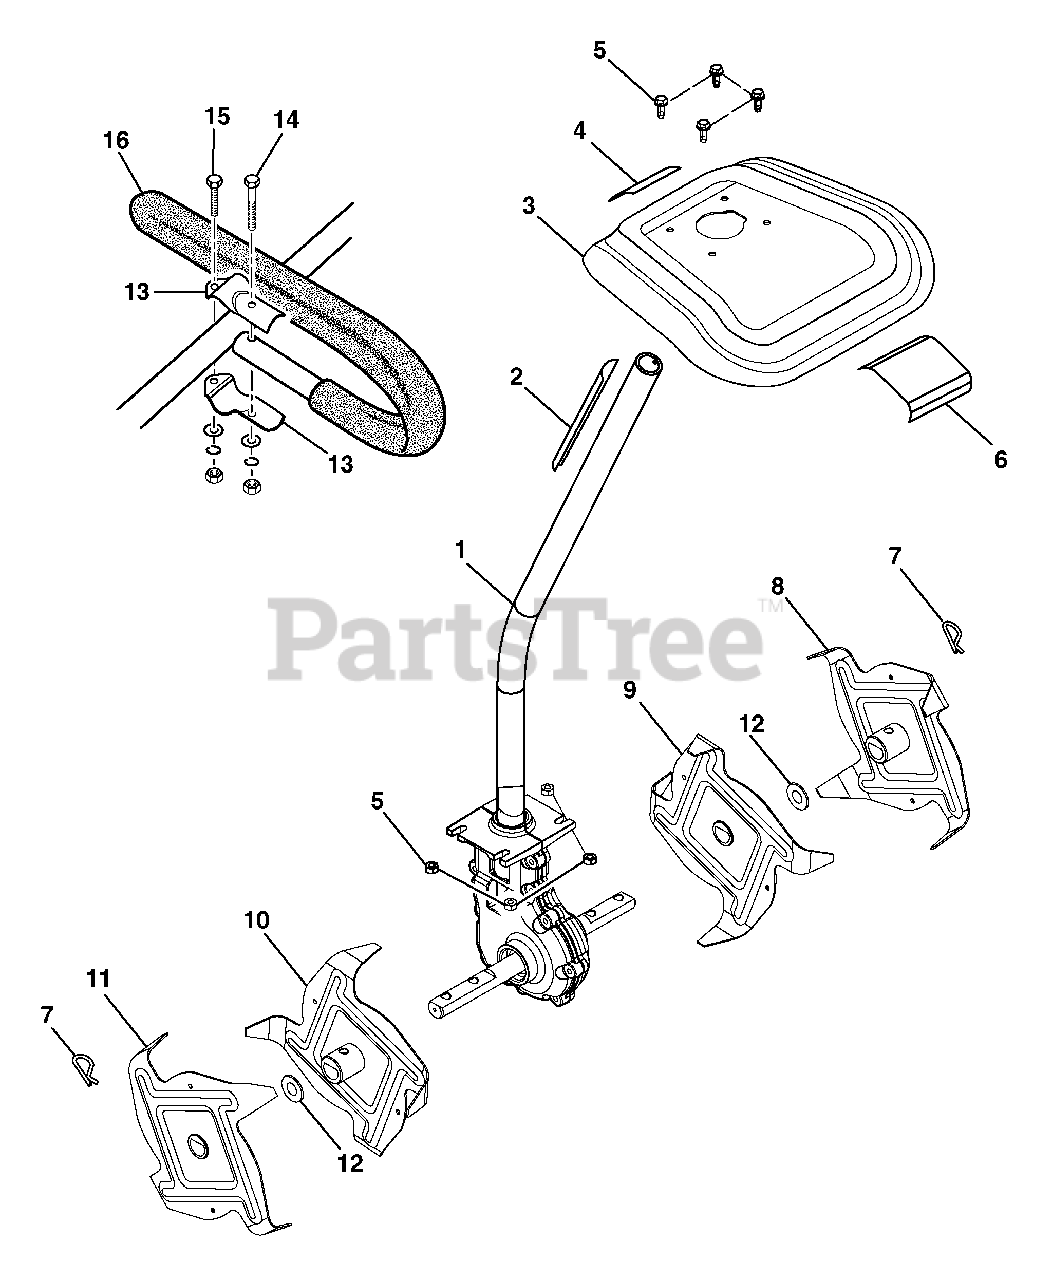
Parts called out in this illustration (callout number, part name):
1	GEAR CASE AND BOOM ASSEMBLY
2	WARNING LABEL
3	TILLER SHIELD
4	EXPAND-IT TILLER DECAL
5	SCREW AND LOCK NUT
6	WARNING LABEL
7	CLIP PIN
8	TINE D ASSEMBLY
9	TINE C ASSEMBLY
10	TINE B ASSEMBLY
11	TINE A ASSEMBLY
12	FELT WASHER
13	HANDLE BAR CLAMP
14	BOLT ASSEMBLY (LONG)
15	BOLT ASSEMBLY (SHORT)
16	J-HANDLE AND GRIP
